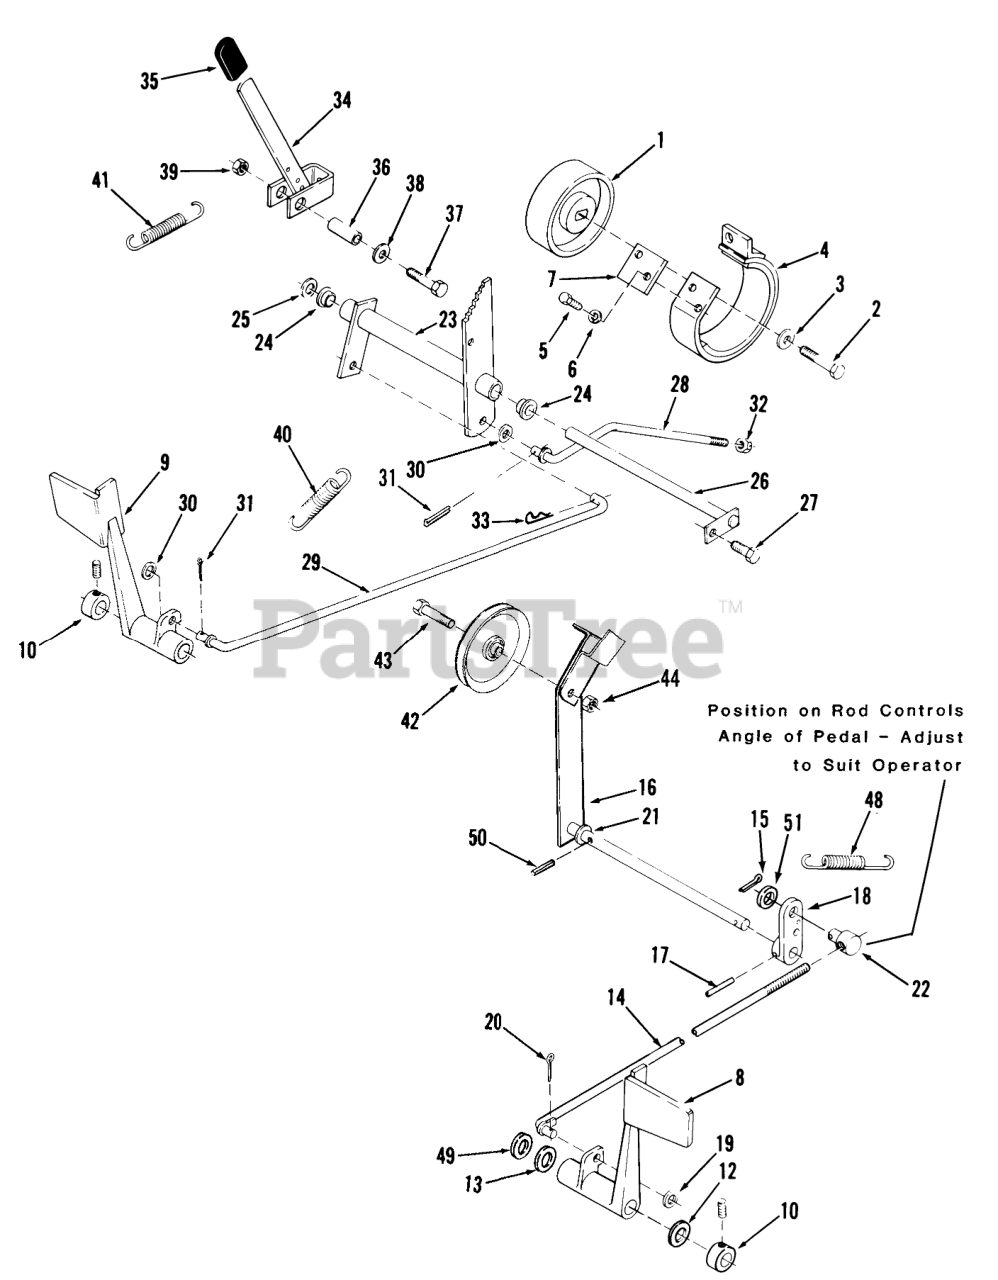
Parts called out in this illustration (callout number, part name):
1	DRUM-BRAKE
2	SCREW-HEX HD CAP
3	WASHER
4	BRAKE BAND ASM
5	H H C S
6	Washer
7	Plate-Stop
8	Pedal-Clutch
9	Pedal Brake
10	COLLAR
12	WASHER-BOWED
13	WASHER
14	ROD AND GUIDE ASM
15	Cotter Pin
16	ASSY-IDLER ARM R
17	PIN-SPIROL
18	Arm-Clutch Rod
19	WASHER-NYLON
20	Pop Rivet
21	SHIM-WASHER
22	TRUNNION
23	Bellcrank Assy
24	BUSHING-FLANGED
25	Washer
26	ROD ASM
27	SCREW
28	ROD-REAR BRAKE
30	WASHER-NYLON
31	Pop Rivet
32	NUT
33	Hairpin
34	ASSY-BRAKE LEVER WAB
35	GRIP
36	SPACER
37	Bolt
38	Washer
39	LOCKNUT-FLANGE
40	SPRING-BRAKE
41	SPRING-EXTENSION
42	PULLEY-IDLER
43	BOLT-SPECIAL HEX
44	Nut
48	SPRING-CLUTCH
49	Washer
50	PIN-SPIROL
51	Washer
